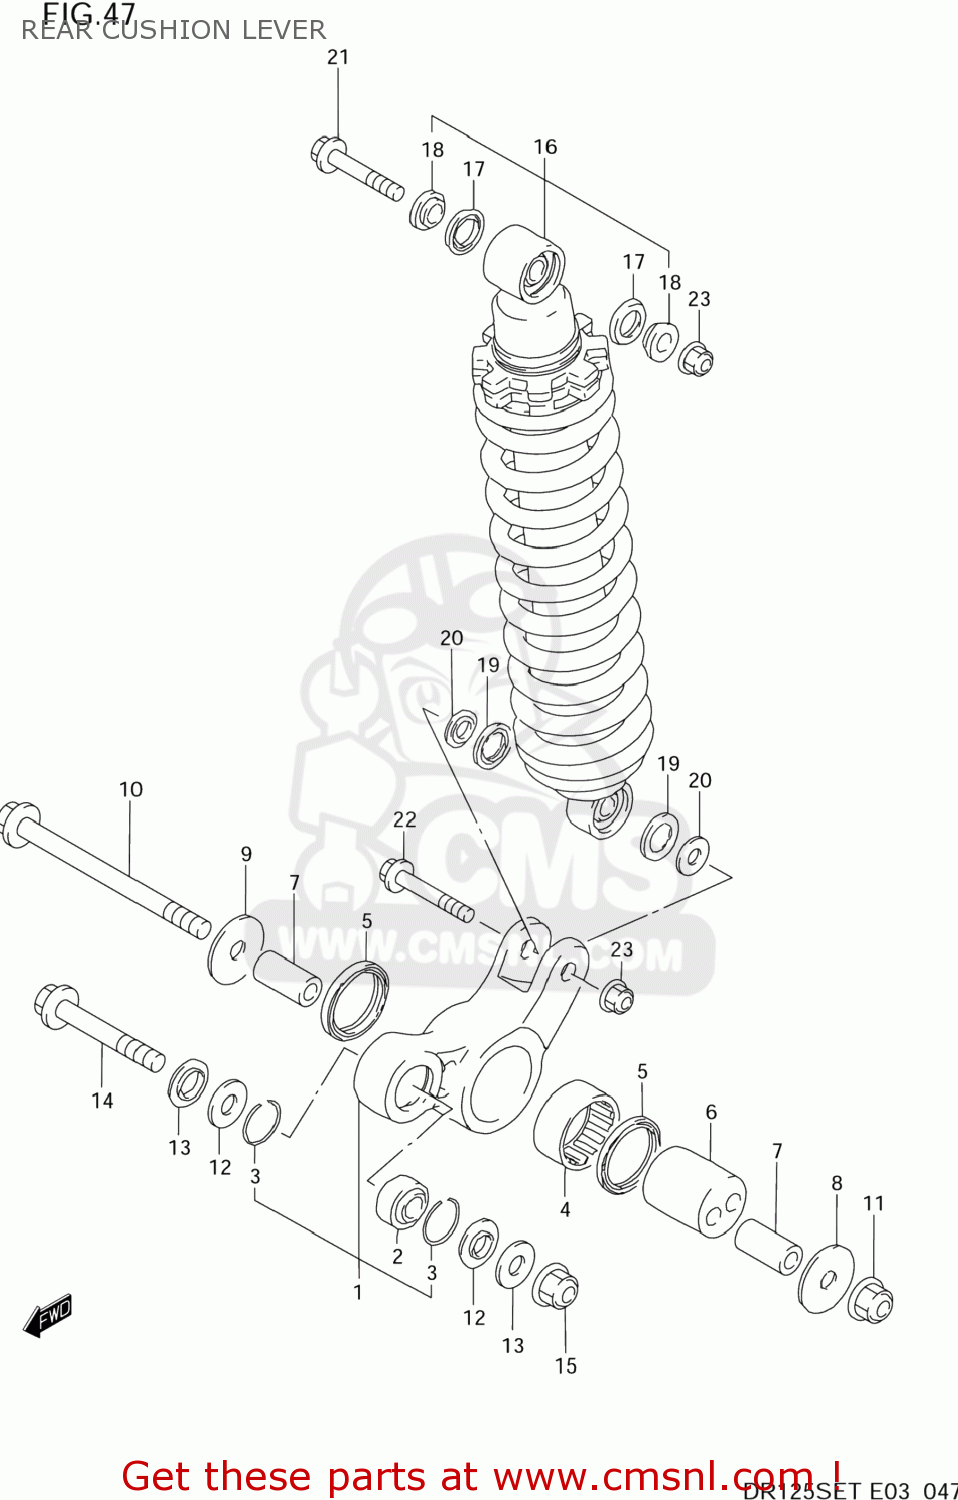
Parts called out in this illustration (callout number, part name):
1	LEVER SET,RR CUSHION
2	BEARING(12X26X16)
3	RING,BEARING STOPPER
4	BEARING(37X47X20)
5	SEAL,DUST
6	SPACER,RR SUSPENSION ECCENTRIC
7	SPACER,CUSHION LEVER SHAFT
8	WASHER,RR CUSH LVR CTR,L
9	WASHER,RR CUSH LVR CTR,R
10	SHAFT,RR CUSHION LEVER CTR
11	NUT 12MM
12	SEAL,RR CUSHION ROD DUST
13	SPACER,RR CUSHION ROD
14	BOLT,CUSHION LEVER FR
15	NUT 12MM
16	ABSORBER ASSEMBLY,REAR SHOCK
17	DUST SEAL
18	SPACER
19	DUST SEAL,RR SHOCK
20	COLLAR
21	BOLT,REAR SHOCK ABSORBER
22	BOLT(10X48)
23	NUT
